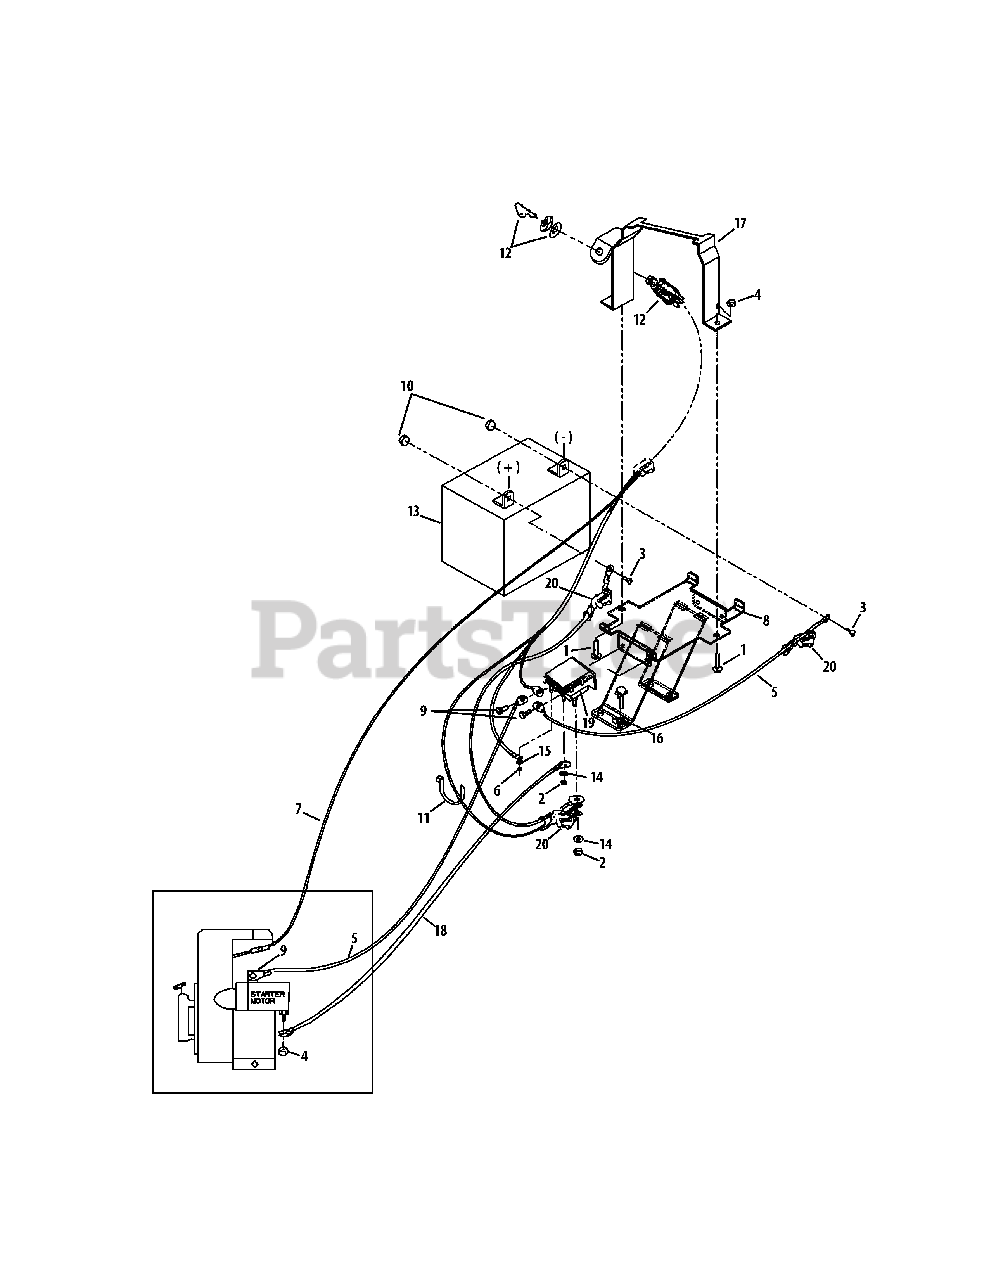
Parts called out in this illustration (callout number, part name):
1	Carriage Screw 1/4-20 x 1.25
2	Hex Nut 5/16-24
3	Flange Screw 1/4-20 x .625
4	Hex Locknut 1/4-20
5	Cable (Ground Wire)
6	Hexlock Washer Nut, 10-32
7	Electric Start Harness
8	Battery Bracket Assembly
9	Self-tapping Screw 1/4-20 x .5
10	Hex Nut 1/4-20
11	Cable Tie
12	Ignition Switch
13	Battery 270 CCA
14	Lock Washer 5/16
15	Lock Washer #10
16	External Lock Washer 5/16
17	Keyswitch Clamp
18	Cable
19	Solenoid
20	Insulating Boot
